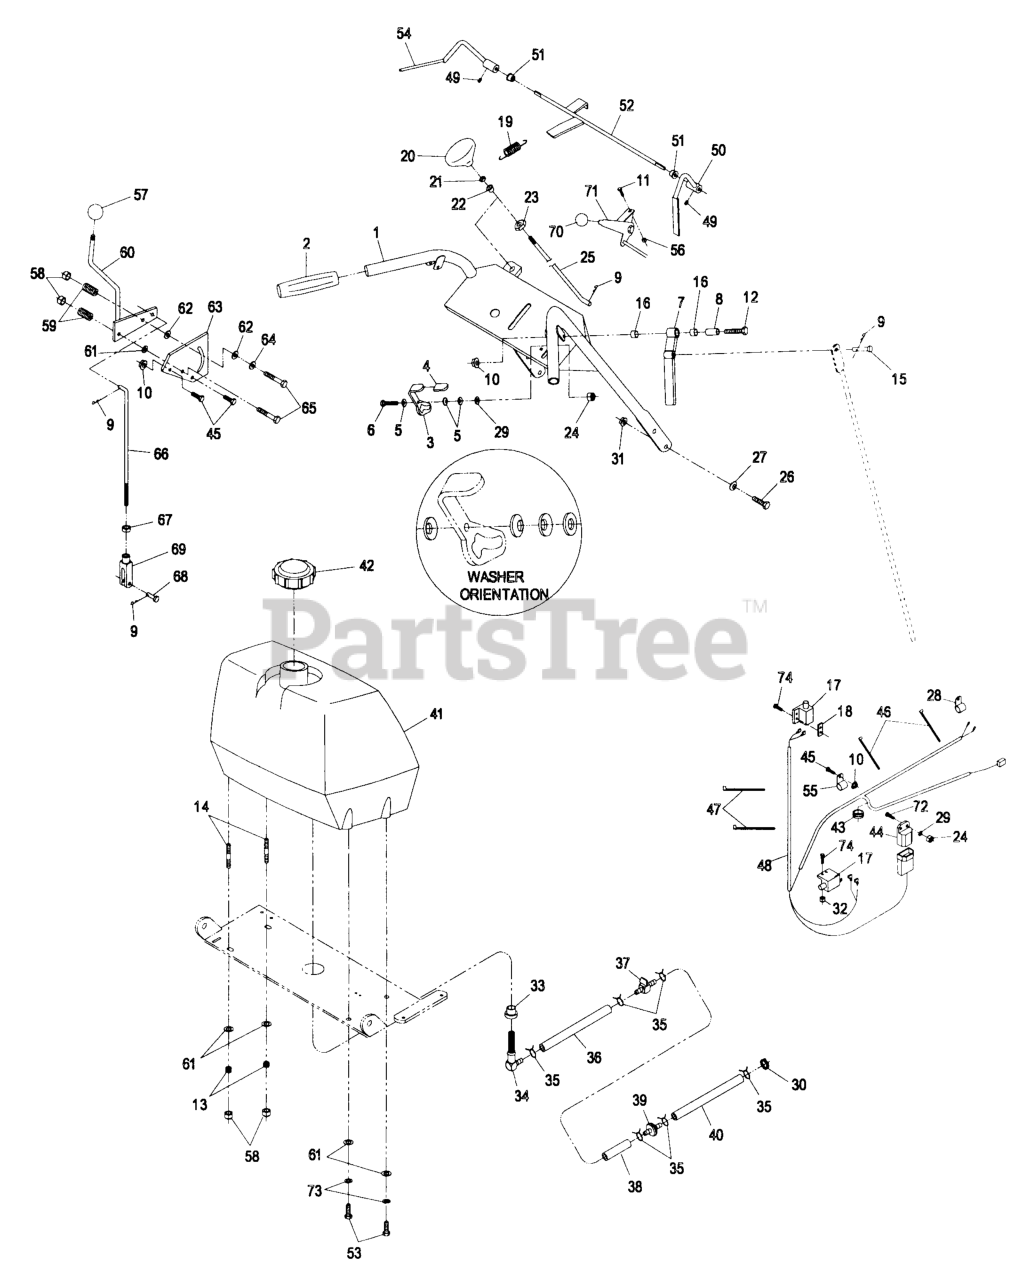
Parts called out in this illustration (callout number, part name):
4	GRIP-LATCH
5	WASHER-SPRING
8	BUSHING-LEVER, DRIVE
9	PIN-COTTER
11	BOLT-CARR
13	SPRING-TANK, FUEL
14	STUD
15	PIN-CLEVIS
16	BUSHING-SLEEVE
17	SWITCH-OPEN, NORMALLY
18	PLATE-TAPPED
19	SPRING-EXTENSION
20	KNOB-PUSH / PULL
22	BEARING-NYLON
23	NUT-PUSH
25	LINKAGE-BLADE
28	CLIP-LOOM
30	CLAMP-HOSE
32	NUT-SQH
34	ELBOW-TANK, FUEL
35	CLAMP
36	HOSE-FUEL
37	VALVE-FUEL
38	HOSE-LINE, FUEL
40	HOSE-LINE, FUEL
42	CAP-FUEL
43	GROMMET
44	MODULE-INTERLOCK
46	TIE-CABLE
47	TIE-PLASTIC
48	WIRHRNS,VH36" 14HP KAW
49	SCREW-SET
50	LEVER-RH
51	BUSHING-NYLON
52	WLD,ROD OPC
54	LEVER-LH
55	CLIP-LOOM
57	KNOB-BALL
59	SPRING-COMPRESSION
62	WASHER-FRICTION
63	PLATE-LEVER, SHIFTER
64	WASHER-FRICTION
66	ROD-CONTROL, SPEED
68	PIN-CLEVIS
69	YOKE-ADJUSTABLE
70	KNOB-BALL
71	CABLE,THROTTLE CONTROL
73	WASHER-LOCK
